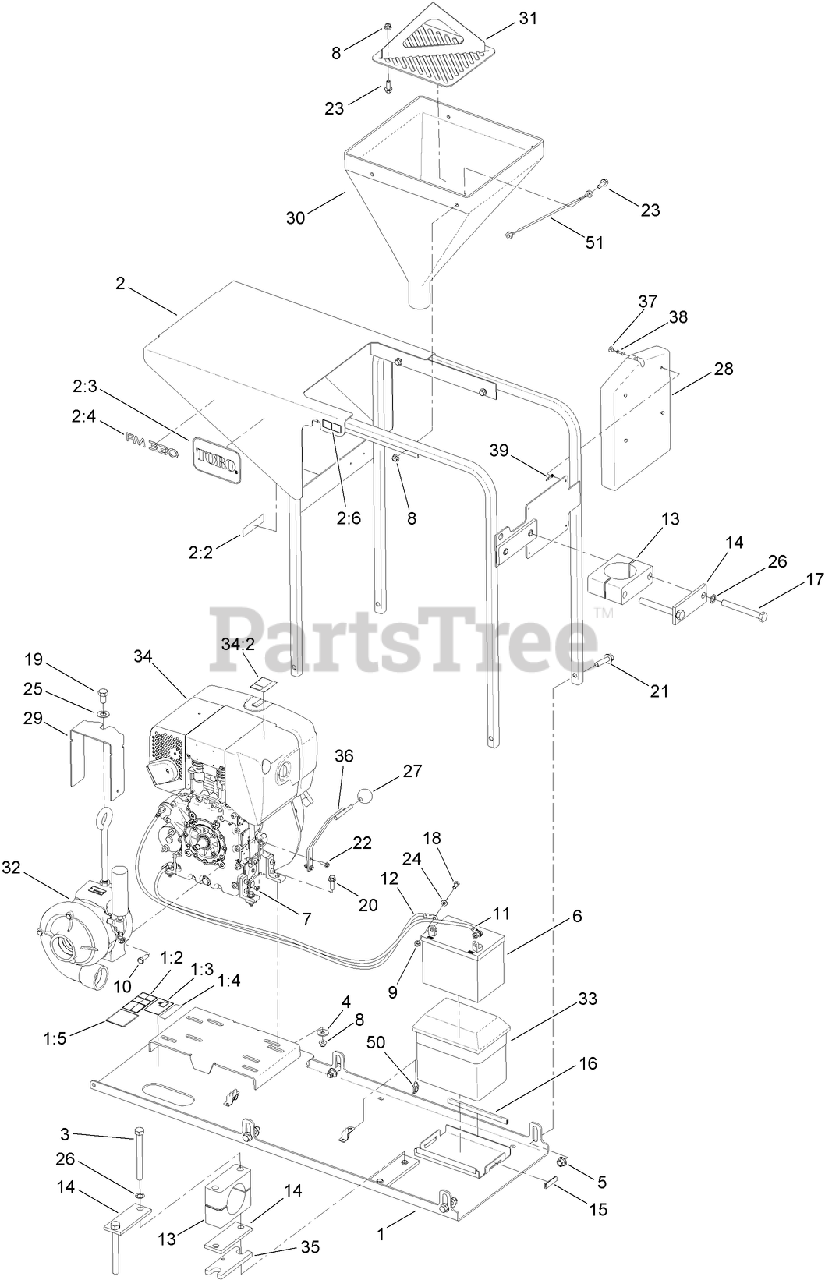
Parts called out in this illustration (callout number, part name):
1	BASE FRAME ASM
1:2	DECAL-WARNING, MIXER
1:3	DECAL-DRAIN
1:4	DECAL-DANGER
1:5	DECAL-LOW SULFER DIESEL
2	HOPPER SUPPORT ASM
2:2	DECAL-ARRESTER, SPARK
2:3	DECAL
2:6	Decal-Warning, Puncture
4	WASHER-HARDENED
5	NUT-LOCK
6	BATTERY
7	NUT-HHF
8	NUT-HF, NI
9	NUT-HHF, SMOOTH
10	SCREW-HH
11	CABLE-BATTERY, NEGATIVE
12	CABLE-BATTERY, POSITIVE
13	CLAMP-PIPE
14	PLATE-CLAMP
15	TRIM-STRAP, BATTERY
16	TRIM-TANK
17	SCREW-HH
18	SCREW-HH
19	SCREW-HH
20	SCREW-HHF
21	SCREW-HHF
22	SCREW-HHF
23	SCREW-HHF
24	WASHER-PLAIN
25	WASHER-FLAT
26	WASHER-FLAT
28	HOLDER-MANUAL, OPERATOR
29	GUARD-COUPLER, ROTATING
30	HOPPER-MIX
31	CUTTER-BAG
32	PUMP ASM
33	BOX-BATTERY
34	ENGINE ASM
34	ENGINE-DIESEL
34:2	DECAL-WARNING, THROTTLE
36	HANDLE-THROTTLE
38	POST-MANUAL
39	LANYARD
50	CLIP-TIE
51	LANYARD-GATE
